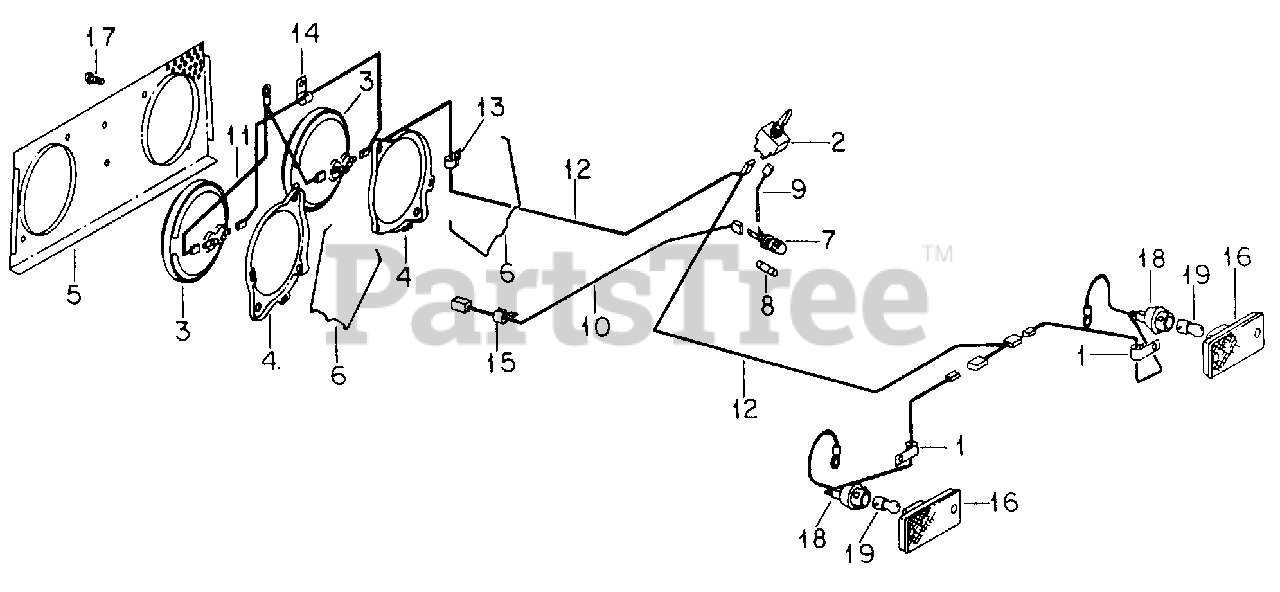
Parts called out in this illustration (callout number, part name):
1	Clip, Taillight
2	Switch, Lighting
3	Light, Sealed Beam Head
4	Retainer, Headlight
6	Spring, Headlight Retaining
7	Holder, Fuse
8	Fuse, 10 Amp
9	Cable Assy, Fuse to Switch
10	Cable Assy, Diode to Fuse
11	Cable Assy, Headlight Ground
12	Cable Assy, Lighting
13	Clip, Cable, Grille Side
14	Clip, Cable, Grille Top
15	Not used in this application
16	Lens Assy, Taillight
17	Screw, Tapping
18	Cable Assy, Taillight
19	Bulb, Taillight #194
